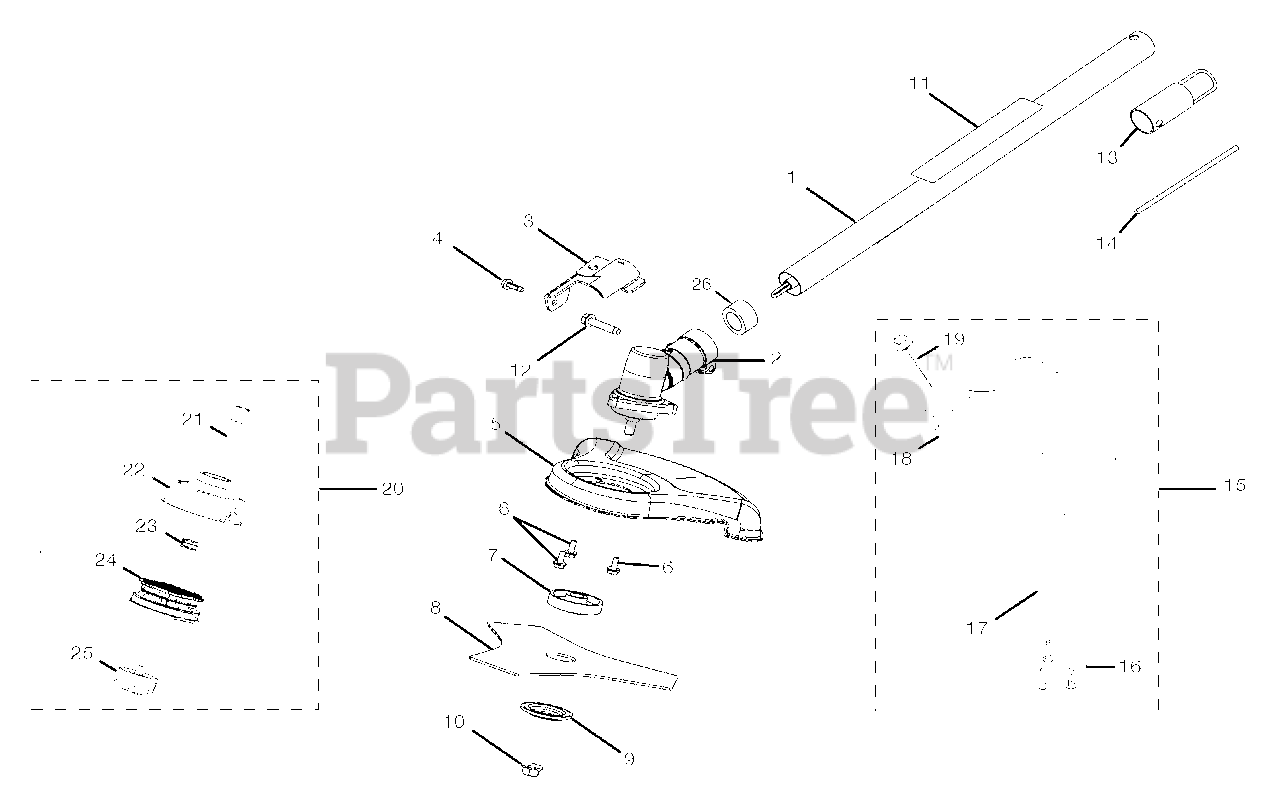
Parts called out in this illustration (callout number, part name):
1	Straight Shaft Assembly
2	Gear Case Assembly
3	Grass Deflector Clamp
4	Screw(#10-24 X 5/8 in. Hex Washer Head, Tri-Lobular)
5	Brushcutter Guard
6	Screw (#10-24x 1/2 in., Sems Slotted Hex Head)
7	Flanged Washer
8	Blade (Tri-Arc(TM))
9	Cupped Washer
10	Blade Nut,Left-handed threads
11	Warning Label
12	Screw(#1/4-20 x 1-1/4 in. Hex Washer Hd., Mach.)
13	Storage Cap
14	Head Locking Tool
15	Grass Deflector Assembly
17	Line Cutting Blade
18	Grass Deflector
19	Screw(#1/4-20 x 1-1/4 in. Hex Washer Hd., Mach.)
20	Trimmer Head Assembly
21	Trimmer Head Shaft Adaptor
22	Trimmer Head
23	Compression Spring
24	Spool with Line (.095)
25	Retaining Cap,Left-handed Thread
26	Spacer
